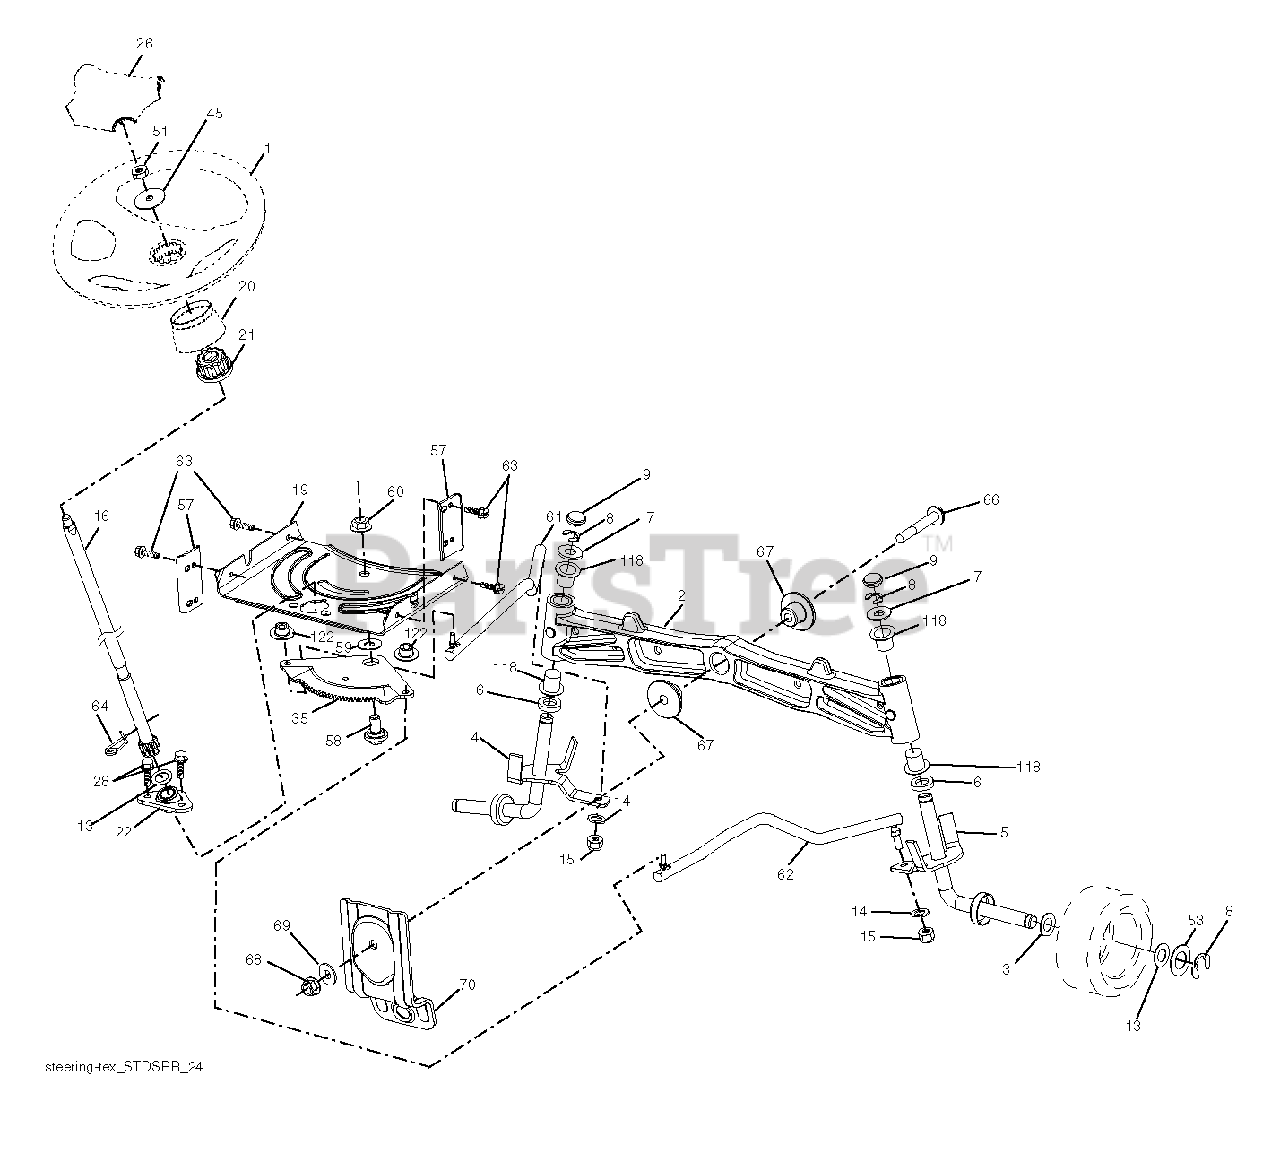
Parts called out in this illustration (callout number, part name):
1	WHEEL.STEERING.STDSRR.BLK/OV
2	AXLE.SVC.ASM CAST IRON.TEX
4	SPINDLE.WELDED.LH.15"TEX
5	SPINDLE.WELDED.RH.15"T
8	RING CLIP
9	CAP.SPINDLE
14	WASHER, LOCK 3/8
15	NUT CROWNLOCK 3/8-24
16	SHAFT.STEER.STEALTH.DD
19	PLATE.STEER.DDL.NLT/NG
21	ADAPTER, WHEEL STNG..
22	STEERING.SUPT.LOWER.
26	CAP.WHL.STRNG.STDSRRD.SRS.BLK
28	SCREW, 3/8-16X3/4
35	GEAR.SECTOR.PLATE.DDL.
45	WASHER 9/16"ID, 2 3/8"OD
51	NUT.HEX.1/2-20
53	WASHER.HARDENED
57	BRACKET.UPSTOP.TEX
58	BOLT.SHOULDER.SECTOR.P
59	WASHER.THURST.SECTOR.S
60	NUT FLANGE LOCK 5/8-11
61	DRAGLINK.LH.BALLSTUD.D
62	DRAGLINK.RH.BALLSTUD.D
63	SCREW
64	RETAINER.CLIP.SPRING.S
66	BOLT HEX FGHD 7/16-14 X 3 SERR
67	BUSHING.PM.FRONT AXLE
68	NUT.LOCK.FLANGE.7/16
69	WASHER.1.5X.505X.118
70	BRKT.DECK.SUSPENSION.F
118	BUSHING, AXLE CAST
